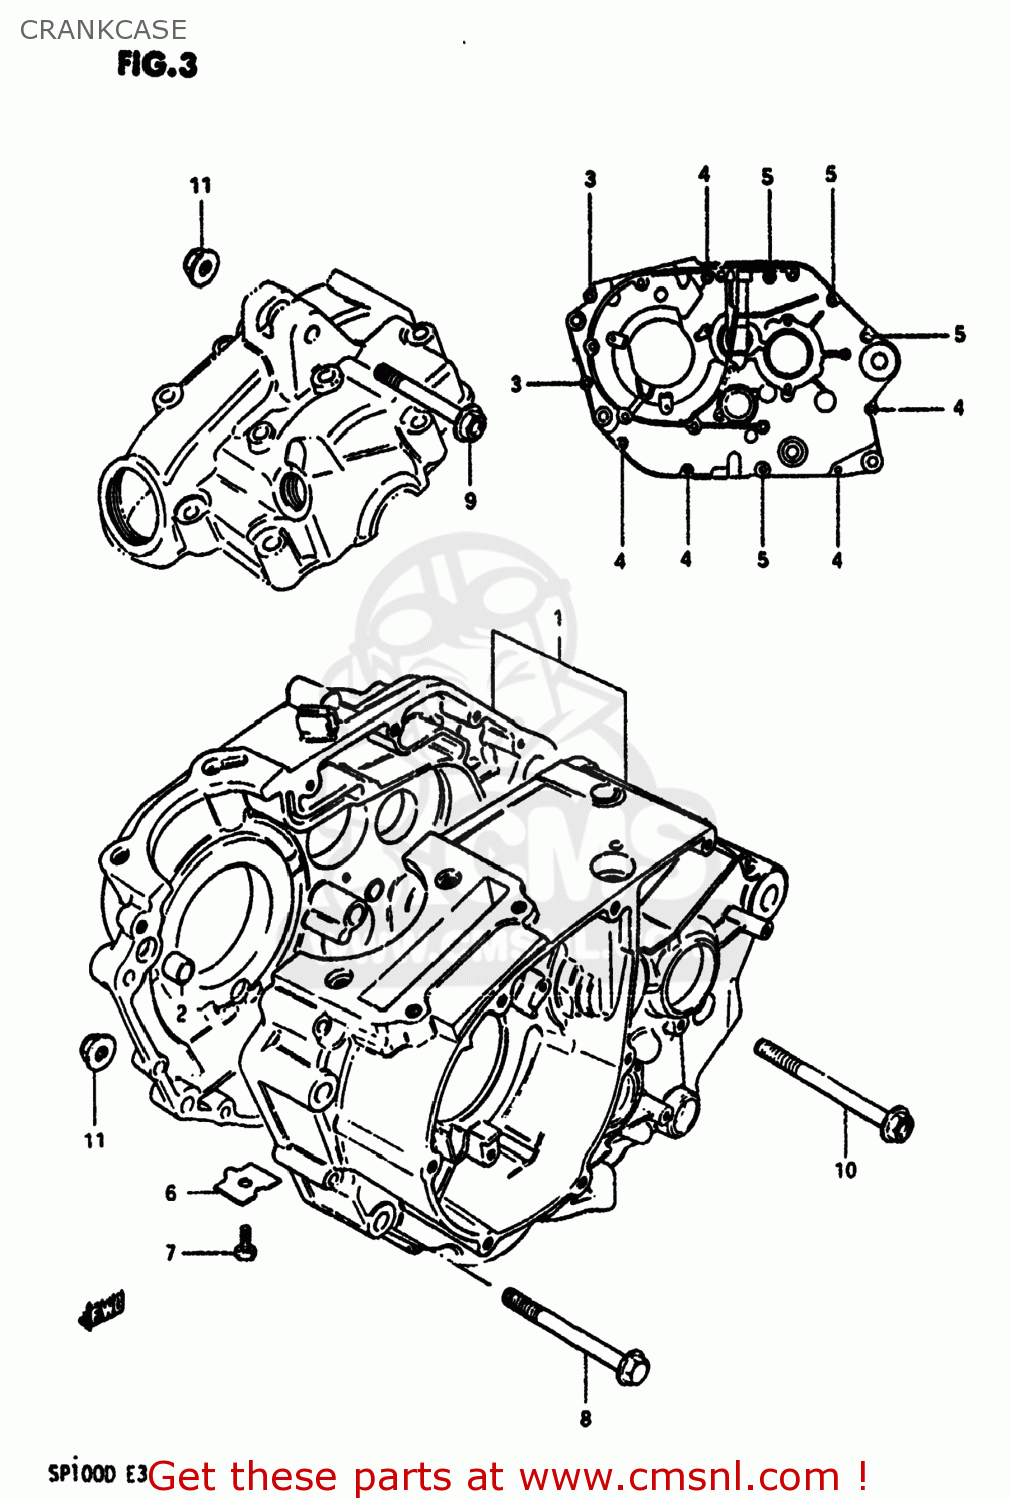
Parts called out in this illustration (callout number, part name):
1	CRANKCASE SET
2	PIN
3	BOLT
4	BOLT
5	BOLT
6	PLATE,OIL GALLERY PLUG
7	BOLT
8	BOLT(8X80)
9	BOLT(8X50)
10	BOLT(8X88)
11	NUT
